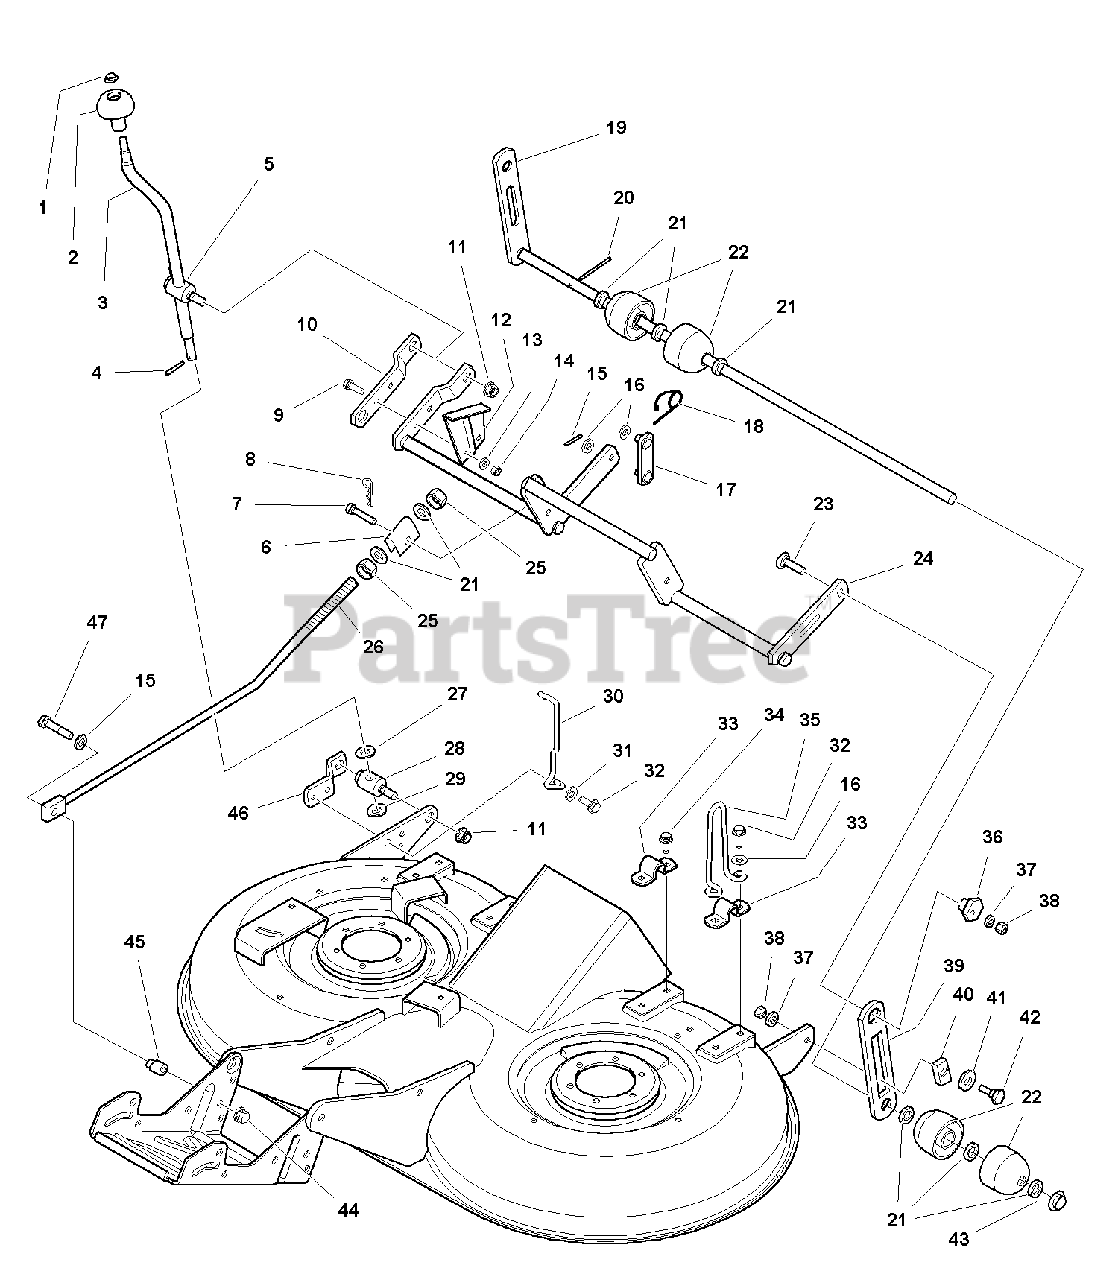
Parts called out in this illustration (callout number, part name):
1	PAL NUT
2	KNOB, Spinner
3	CRANK, Height Adjust
4	PIN, Spring
5	TRUNNION, Rod
6	TRUNNION, Bracket
7	PIN, Round Head, Drilled, 3/8 x 2
8	CLIP, Hair Pin
9	CAPSCREW, Hex Head, 5/16-18 x 1 G8
10	ARM, Rear Adjustable
11	NUT, Hex FlangeTwo-Way Lock, 1/2-13
12	BRACKET, Height of Cut
14	NUT, Hex, 5/16-18 Whiz Lock
15	PIN, Cotter
16	WASHER, 3/8
17	LINK & WELD PINS ASSEMBLY, Lower Lift
18	RETAINER, Pin, Spring
19	SHAFT & BAR ASSEMBLY, Roller
20	PIN, Cotter
21	WASHER, 5/8
23	CARRIAGE BOLT, 3/8-16 x 1-1/2
24	SHAFT & ARMS ASSEMBLY, 40" Rear
25	NUT, Hex, 5/8-11
26	ROD, Adjustment
27	WASHER, 1/2
28	TRUNNION, Threaded
29	WASHER, Detent
30	INDICATOR, Height of Cut
31	WASHER, 5/16
32	SCREW, Hex Washer Head, Taptite, 5/16-18 x 1
33	STRAP, Roller Support
34	SCREW, Hex Washer Head, Taptite, 5/16-18 x 3/4
35	STOP, Up Wire
36	NUT, Hex Adjusting, .99 DIA .687
37	LOCKWASHER, 3/4
38	NUT, Hex, 3/8-16
39	BAR, Roller
40	SLIDE, Roller
41	WASHER, 1/2
42	BOLT, Shoulder, 3/8-16 X 1.34
43	NUT, Push On
44	NUT, Hex lock ESNA Heavy, 3/8
46	STRAP, Trunnion Retainer
47	CAPSCREW, Hex Head, 3/8-16 x 1-3/4
